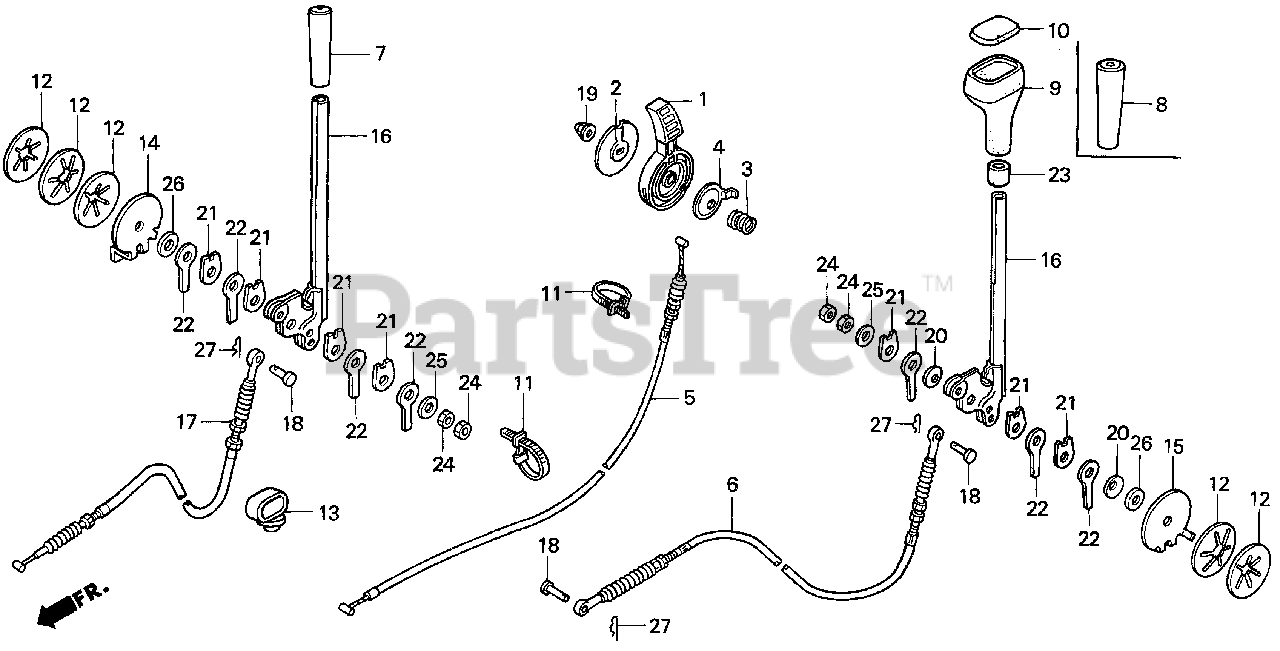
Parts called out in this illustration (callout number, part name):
1	LEVER, THROTTLE
2	PLATE, THROTTLE LEVER
3	SPRING, THROTTLE LEVER
4	SEAT, SPRING
5	CABLE, THROTTLE
6	CABLE, CHANGE
7	GRIP, CHANGE LEVER
8	GRIP, CHANGE LEVER (ORANGE)
9	GRIP, CHANGE LEVER
10	KNOB, CHANGE LEVER GRIP
11	BAND, WIRE
12	SPRING, ADJUSTING ARM
13	GROMMET, WIRE
13	CLAMP, CABLE
14	PLATE, R. STOPPER
15	PLATE, L. STOPPER
16	LEVER, CHANGE
17	CABLE, CHUTE GUIDE
18	PIN, CONTROL BOX SETTING
19	NUT, CAP (6MM)
20	WASHER, LOCK
21	WASHER, FRICTION
22	WASHER, FRICTION SETTING
24	NUT, HEX. (8MM)
25	WASHER, PLAIN (8MM)
27	PIN, LOCK (6MM)
